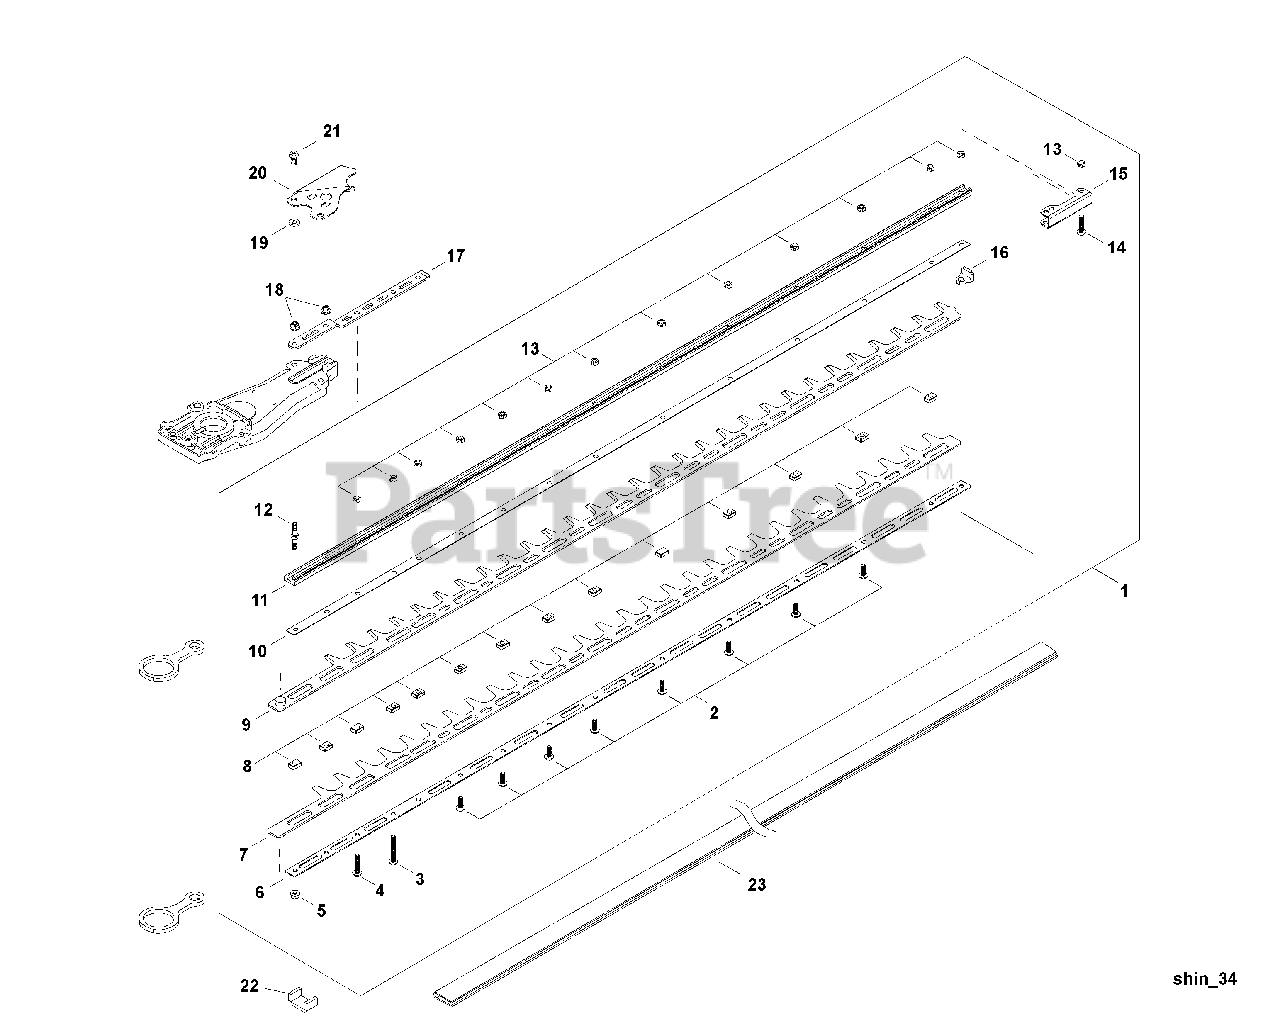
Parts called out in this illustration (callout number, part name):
1	CUTTER ASSY, 40"
2	BOLT M5×14
3	BOLT M5×35
4	BOLT M5×25
6	PLATE, LOWER
7	CUTTER, 40" LOWER
9	BLADE, UPPER 40"
10	PLATE, UPPER
11	BAR, 40" GUIDE
12	STUD, MOUNTING M5
13	NUT, LOCK M5
14	BOLT M5×22
15	PLATE, GUIDE
17	BRACKET, CUTTER
19	WASHER M5
20	PROTECTOR
21	BOLT M6×12
22	PACKING, FELT
23	SCABBARD 40"
